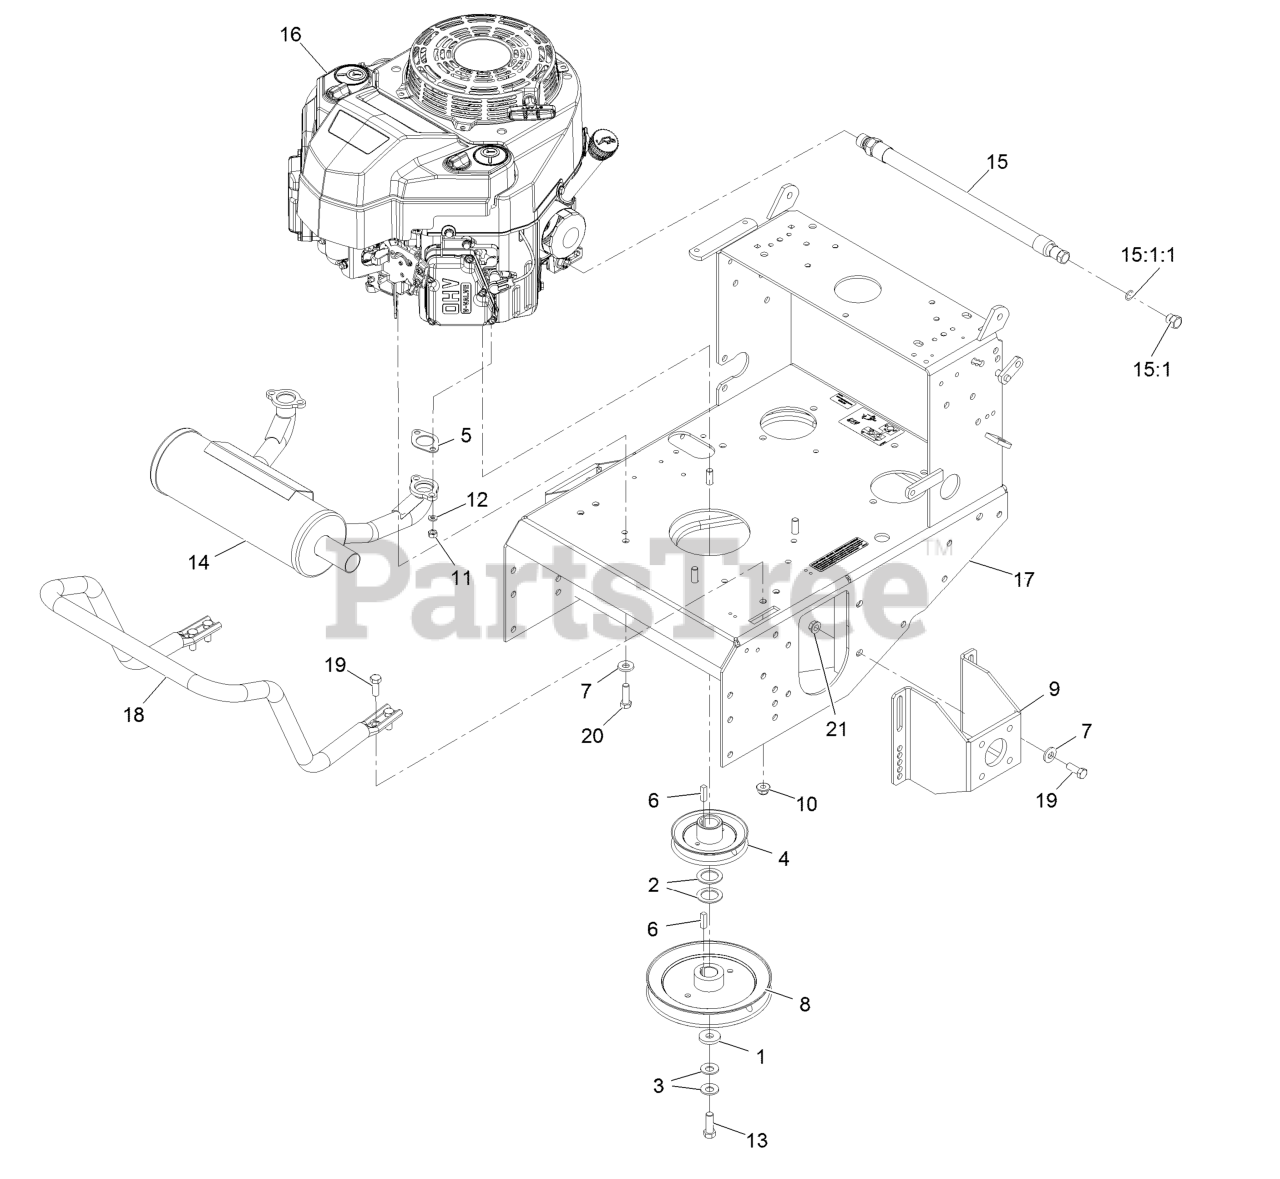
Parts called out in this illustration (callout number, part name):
3	Washer-Spring Disc 7/16
5	Gasket-Exhaust
6	Key-Machine 1/4 X 1/4 X 1
7	Washer-Spring Disc 3/8
8	Sheave
9	Mount-Motor
10	Nut-Nyloc 3/8-16 Flg
12	Washer-Spring Lock M8
13	Screw-HH
14	Muffler-Horizontal
15	Asm-Oil Drain Hose W/Plug
15:1	Plug-W/O-Ring
15:1:1	O-Ring
16	Engine-Kawasaki
17	ASM, Vh Engine Deck W/Decals
18	Guard-Muffler
19	Screw-HH 3/8-16 X 1
20	Screw-HH 3/8-16 X 1 1/4
21	Nut-Whizlock 3/8-16
